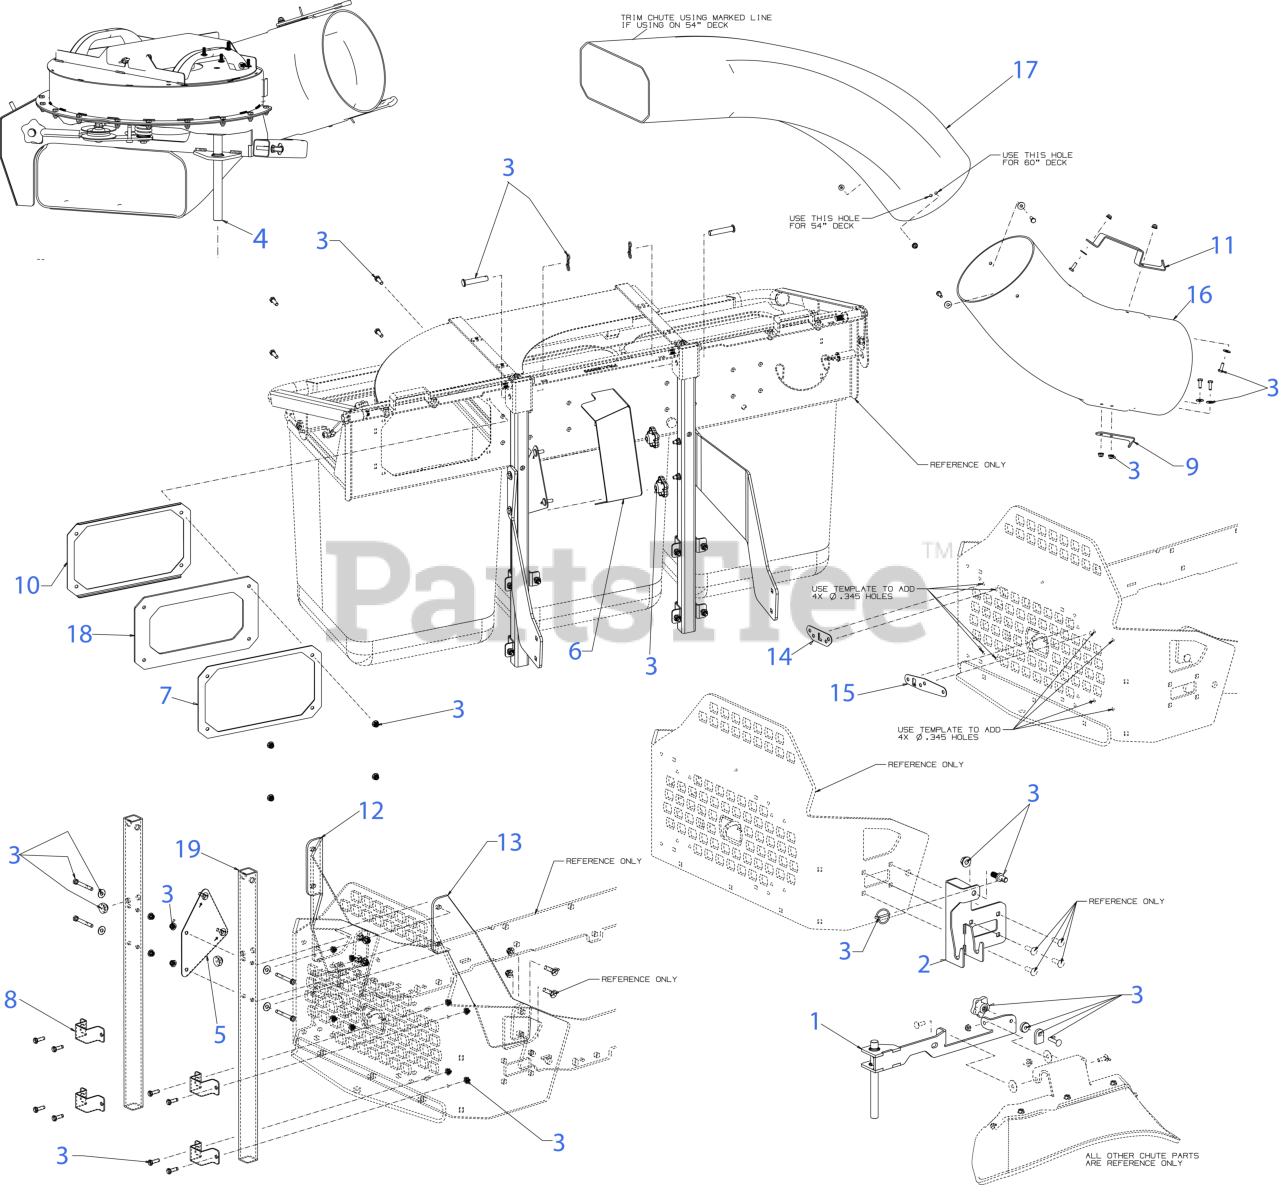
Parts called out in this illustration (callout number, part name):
1	CHUTE BRACKET
2	DISCHARGE CHUTE HOLDER
3	SCREW PACK
4	BLOWER
5	STORAGE COVER BRACKET
6	BELT COVER
7	BAGGER GASKET PLATE
8	BAGGER BRACKET
9	CATCHER CHUTE BRACKET
10	BAGGER GASKET BACK PLATE
11	CHUTE HANDLE BRACKET
12	SUPPORT BRACKET (LH)
13	SUPPORT BRACKET (RH)
14	TEMPLATE PLATE (LH)
15	TEMPLATE PLATE (RH)
16	BAGGER CHUTE (LOWER)
17	BAGGER CHUTE (UPPER)
18	BAGGER GASKET
19	VERTICAL TUBE
